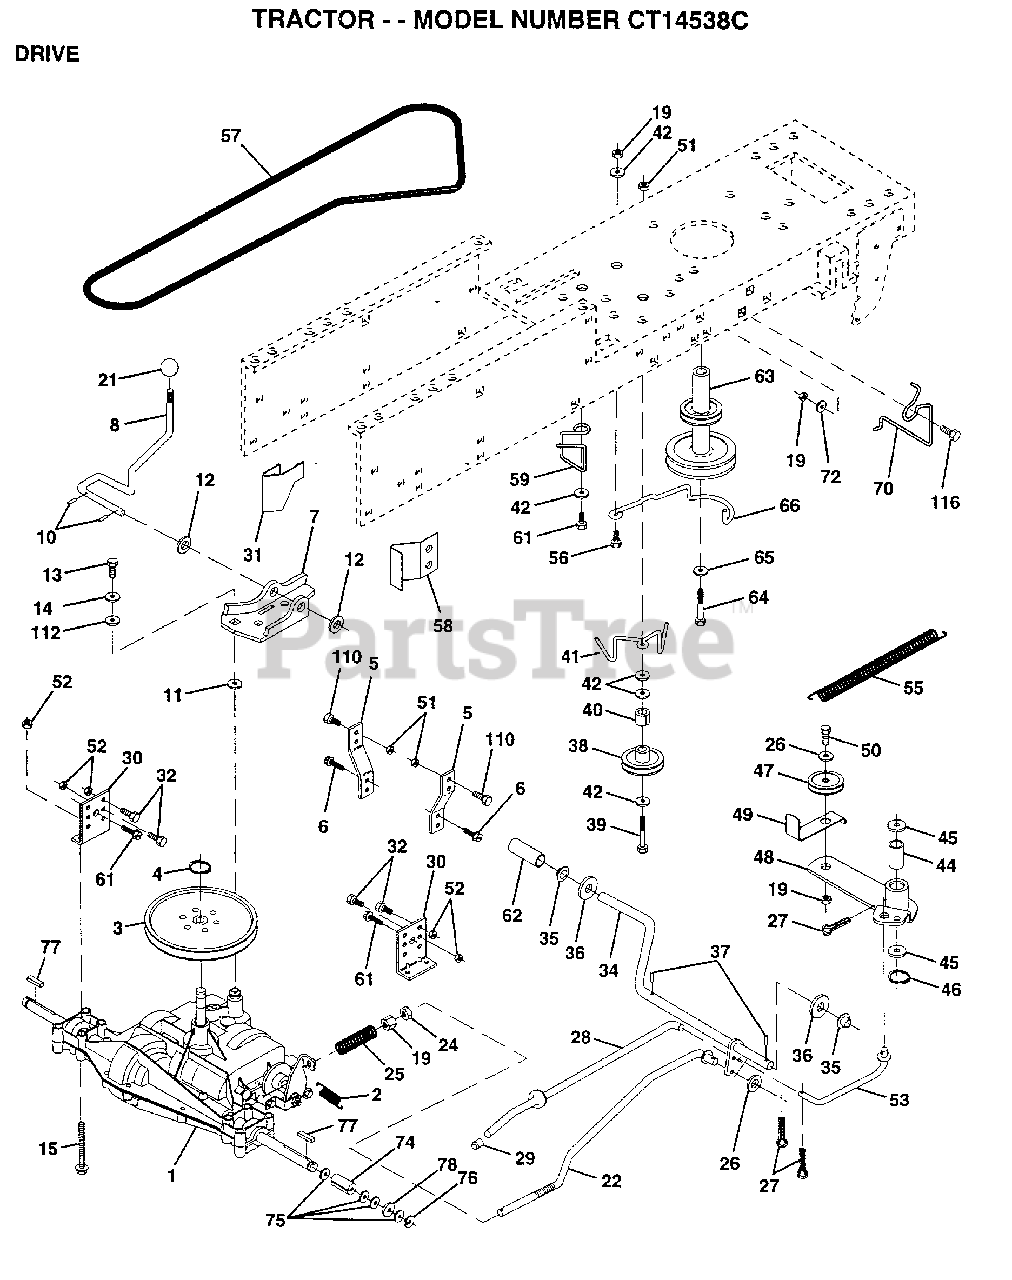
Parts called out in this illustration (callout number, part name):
2	SPRING.BRAKE.RETU
3	PULLEY TRANS
5	STRAP TORQUE
6	SCREW
8	SHIFT ROD
10	PIN COTTER 1/8
11	WASH-SHFT PLT LT
12	WASHER
13	BOLT.1/4-28.W/PAT
14	LOCKWASHER
15	BOLT.HX.FLG.5/16
19	NUT
21	KNOB T (1/2-HOLE)
22	BRAKE ROD
24	NUT
25	SPRING ROD LT
26	WASHER
27	COTTER PIN
28	ROD.BRAKE.PARK.LT
29	PLUNGER CAP T
30	TRANSAXLE MTG BKT
31	"KEEPER,BELT LH T"
32	BOLT
34	SHAFT FOOT PEDAL
35	NYLON BEARING
36	WASHER LT
38	PULLEY.IDLER.FLAT
39	BOLT
40	SPACER T
41	KEEPER BELT
42	WASHER
44	"LY, BEARING"
45	WASHER LT
46	KLIP RING
48	ARM IDLER
49	RETAIN BELT
53	"LINK, CLUTCH T"
55	"SPRING, RETURN LT"
58	"KEEPER,BELT RH T"
59	KEEPER BELT CNTSP
61	SCREW
62	PEDAL COVER T
63	PULLEY.ENGINE
64	BOLT
65	LOCKWASHER
70	KEEPER BELT ENG
72	WASHER
74	SPACER LT
75	WASHER
76	E-RING LT
77	SQUARE KEY
78	WASHER
112	WASHER LT
116	BOLT RDHD 3/8-16
